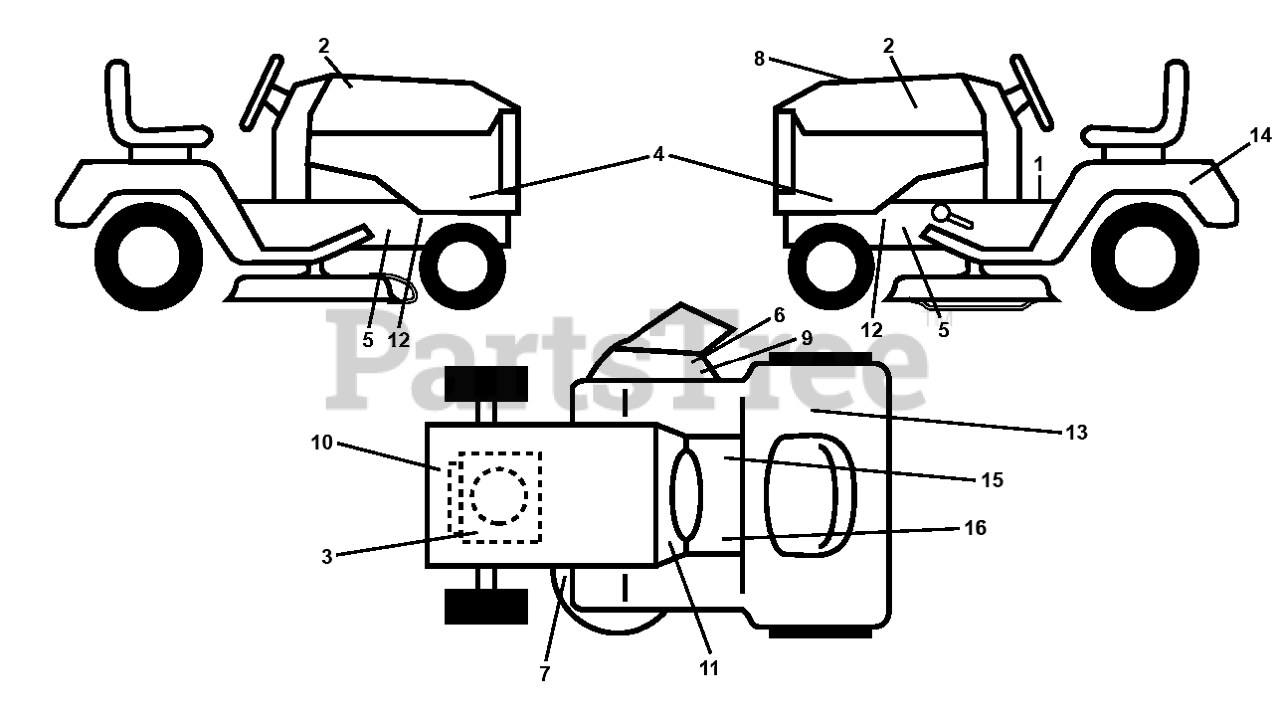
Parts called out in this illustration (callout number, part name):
1	DECAL TRACTOR SADDLE DECAL DEC
1	DECAL.TRACTOR.SADDLE
1	DECAL.READ.OWN.MAN.SYMBOL.LT
2	DECAL.BADGE.170MM.TEXTLOGO.
2	DECAL.WB.178MM.15.HUSQ.NEWBRAN
3	DECAL.ENGINE.WARNING
4	DECAL.SDPNL.HUSQLT.TS138
5	DECAL.WARNING.HOT.MUFFLER.2021
5	DECAL.CHASSIS.HOT.MUFFLER
6	DECAL.DECK.DEFLECTOR.WARNING
6	DECAL, DECK DEFLECTOR, WARNING
7	DECAL.DECK.SCH.36,38,94.NONCR
8	DECAL.RPL.BSM31.INTK.TLW.38.GE
8	DECAL.RP.BSM31.INTK.TLW.38.K46
8	DECAL RPL.BSM31.HUSQ.TLW.38.K4
8	Decals
9	DECAL.DFLCTR.WARNNG.CTFNGR.SYM
10	DECAL.ENG.BSM31.ENDUR.17.5HP
10	DECAL.ENG.B&S.HS.500CC.382338
11	DECAL.SNOWFLAKE.MS498.HUSQ
12	DECAL.WARNING.SERVCE/FIRE
13	DECAL CERTIFICATION DECAL EMCC
14	DECAL BTRY SYMBOLS
15	DECAL.PARKING.BRAKE.SADDLE.LT
16	DECAL.FNDR.SDLE.BRAKE.CLUTCH.6
